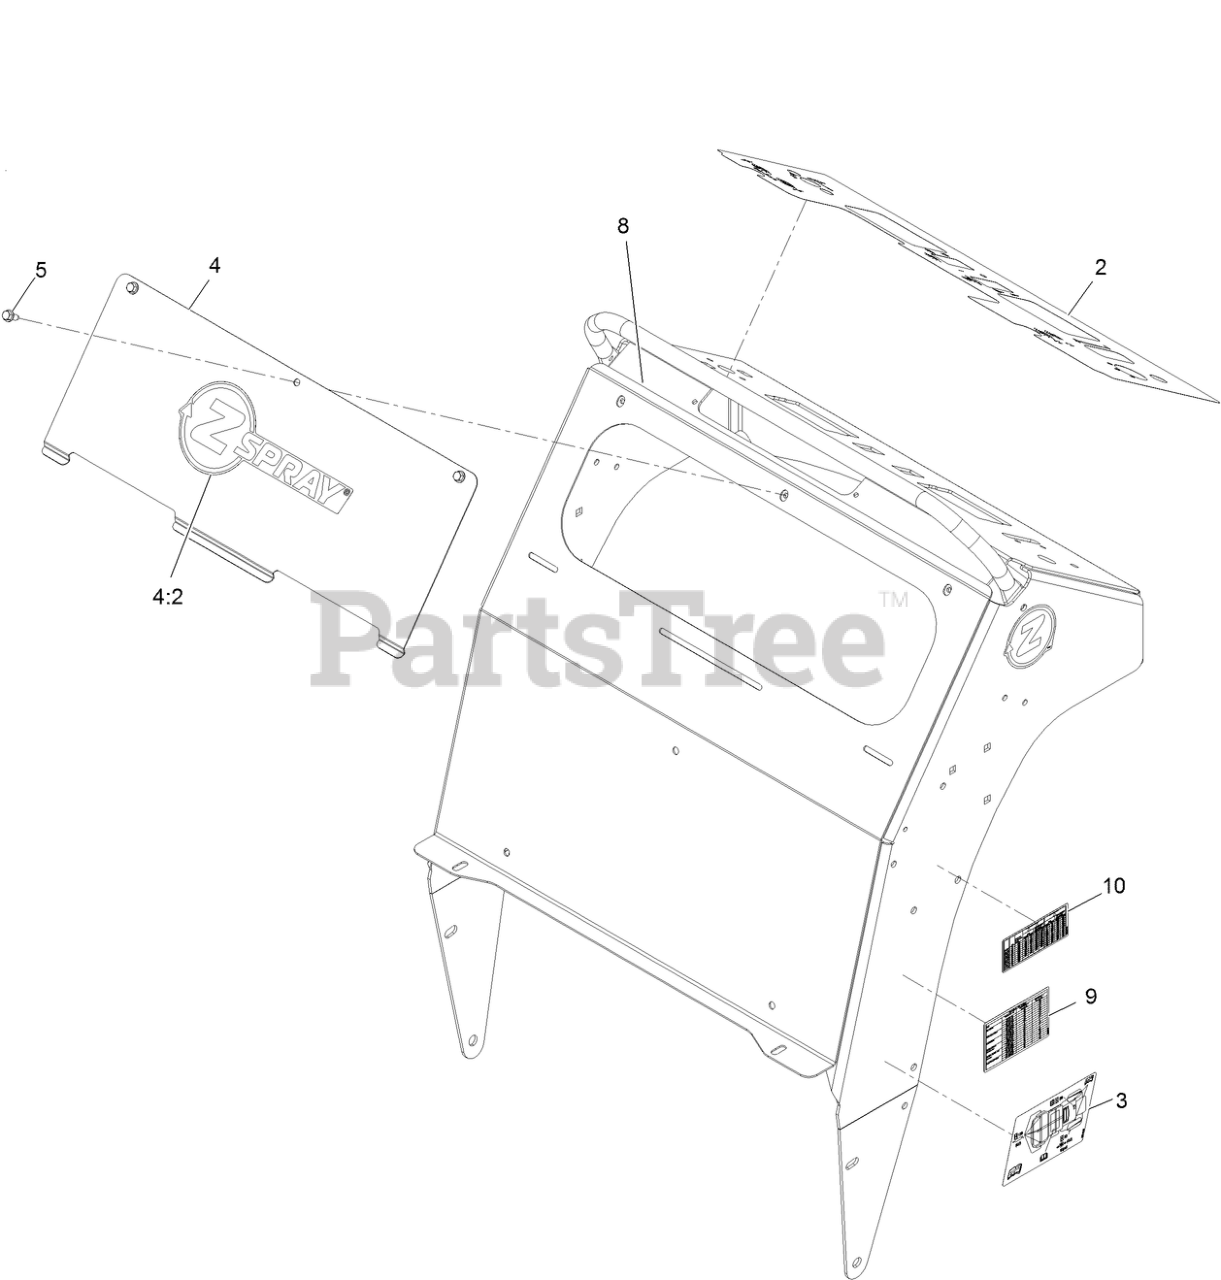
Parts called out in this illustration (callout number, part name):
2	Decal-Control
3	DECAL-SERVICE AID
4	ACCESS PANEL W/ DECAL
4:2	Decal-Z-Spray
5	SCREW-HWH
8	Decal-Z-Logo
9	Decal-Spread Chart
10	Decal-Spray Chart
